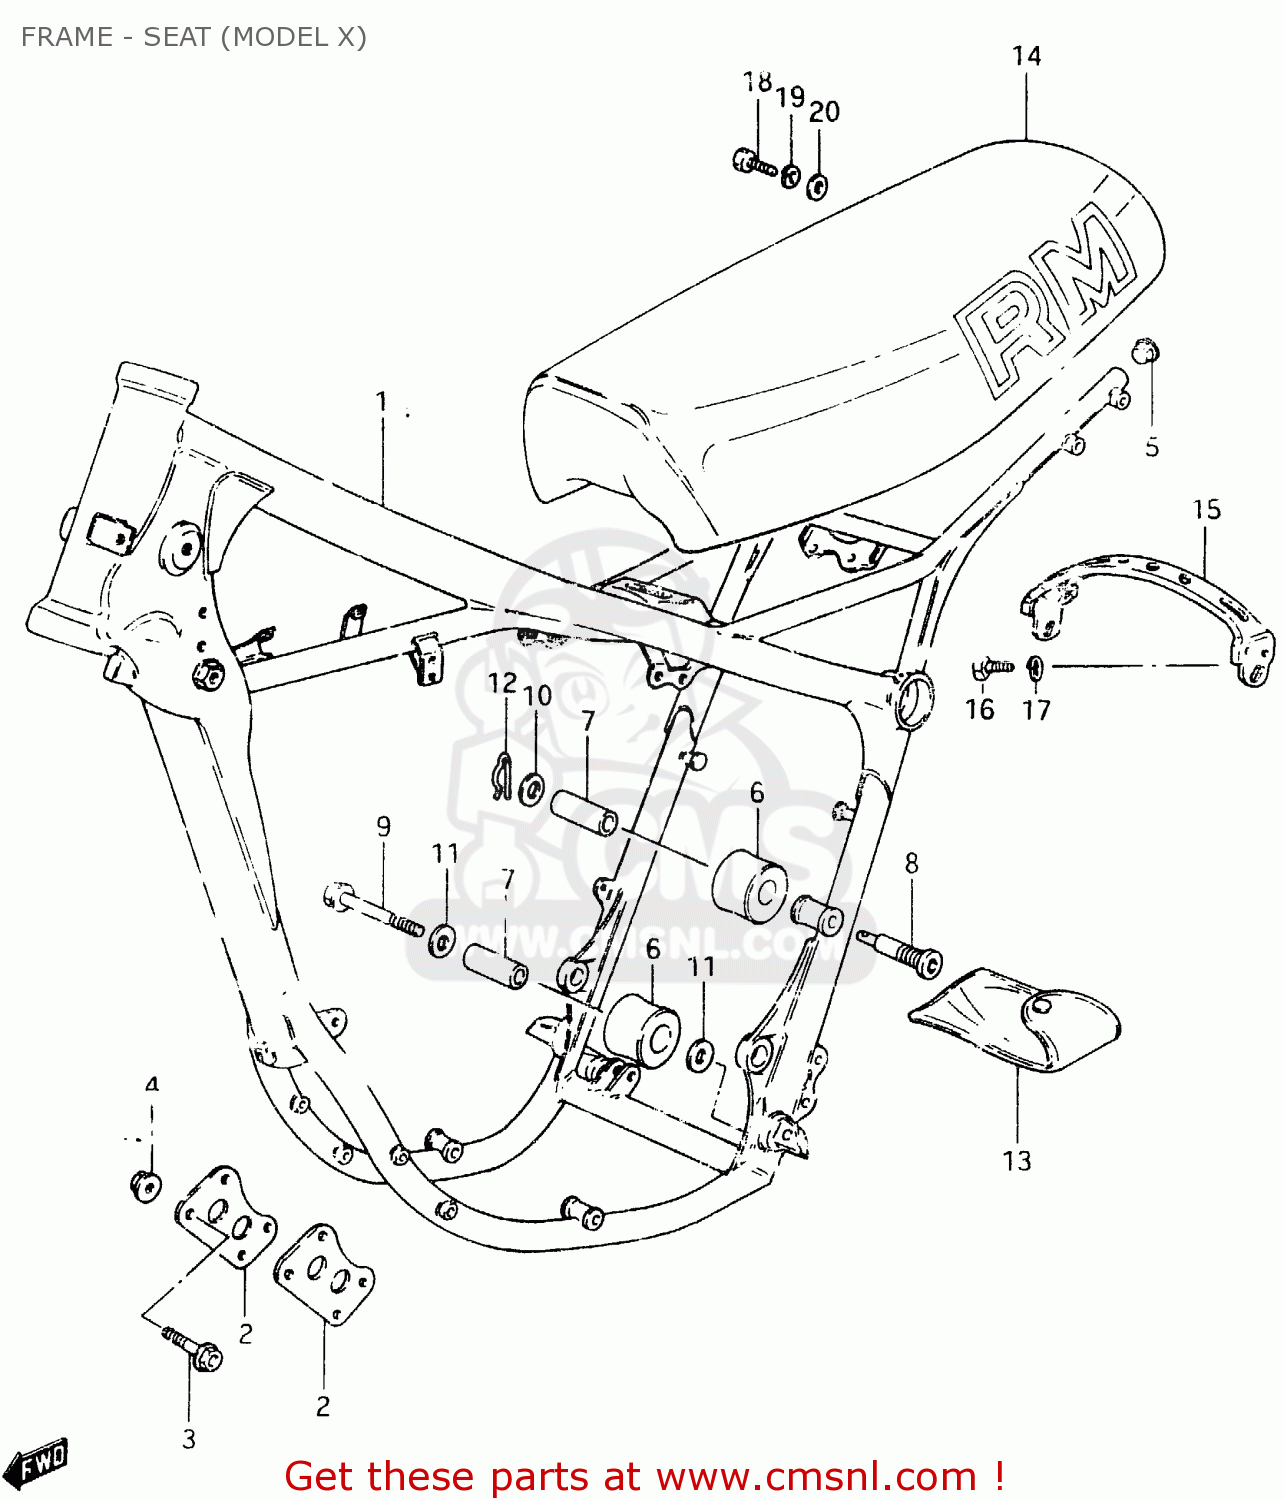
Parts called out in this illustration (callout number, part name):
1	FRAME
2	PLATE,ENGINE MOUNTING
3	BOLT
4	NUT
5	PLUG(OD:17)
6	ROLLER,CHAIN LENGTH CONTROL
7	SPACER,CHAIN LENGTH ROLLER
8	BOLT,CHAIN LENGTH ROLLER
9	BOLT(8X45)
10	WASHER
11	WASHER
12	CLIP
13	TOOL SET
14	SEAT ASSEMBLY
15	PLATE SEAT REAR STAY
16	BOLT, UPPER
17	LOCK WASHER
18	BOLT
19	LOCK WASHER
20	WASHER (8.2X20X1.6)
